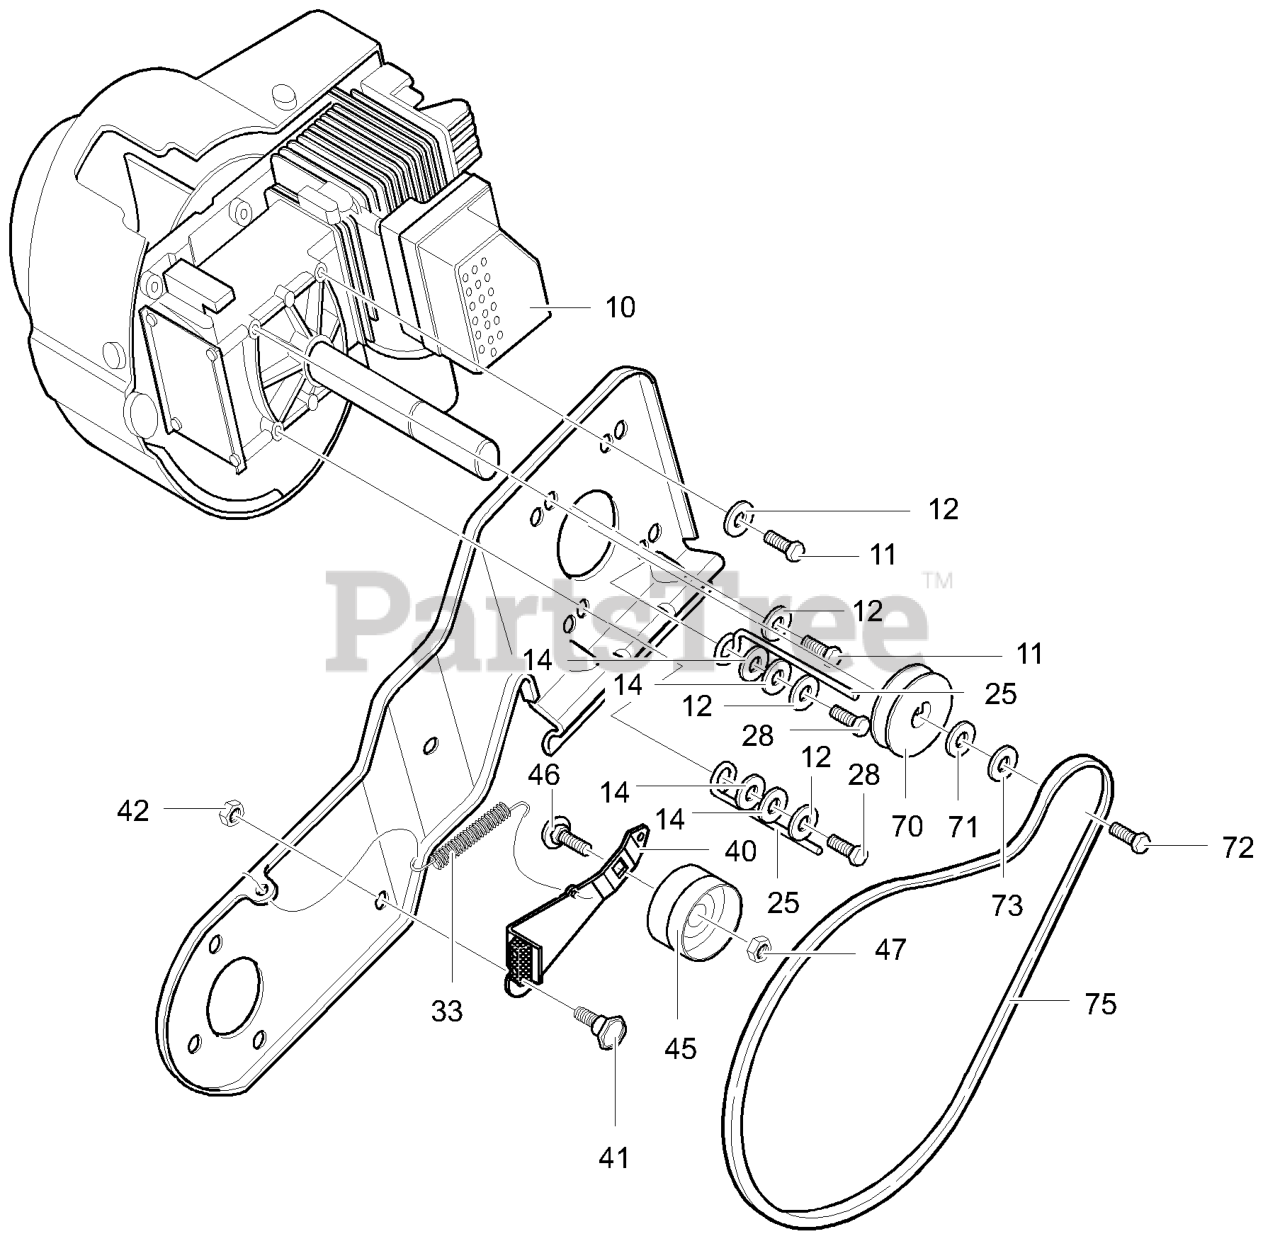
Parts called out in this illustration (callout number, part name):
10	ENGINE
11	SCREW, 5/16-18 x 0.75
12	WASHER
14	WASHER, FLAT
25	GUIDE, BELT
28	SCREW, 5/16-18 x 1.00
33	SPRING, IDLER BRAKE
40	ASSEMBLY, IDLER BRAKE ARM
42	NUT, 5/16-18
45	PULLEY, IDLER
46	BOLT, CARRIAGE
47	NUT, JAM
70	PULLEY, ENGINE
71	WASHER
72	SCREW, 5/16-24 x .75
73	WASHER
75	BELT, V
